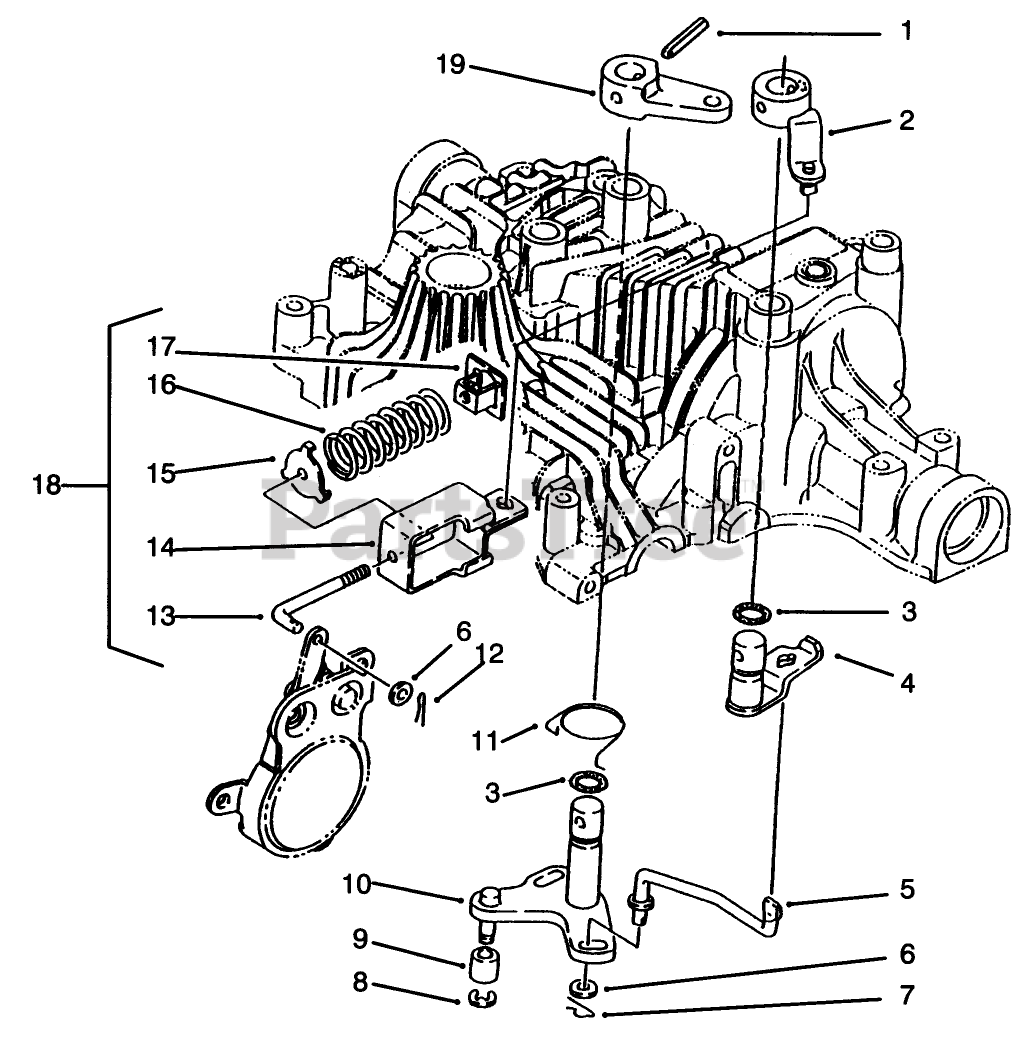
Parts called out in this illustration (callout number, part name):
1	PIN-ROLL
2	ARM-BRAKE B
3	O-RING
4	ARM-BRAKE A
5	ROD-BRAKE
6	WASHER
9	BUSHING
10	SHAFT-BRAKE
11	RETURN-BRAKE
12	PIN-COTTER
13	ROD - ADJUSTER
14	HOLDER - SPRING
15	GUIDE - SPRING
17	ADJUSTER
18	ROD ASM
19	ARM-BRAKE
